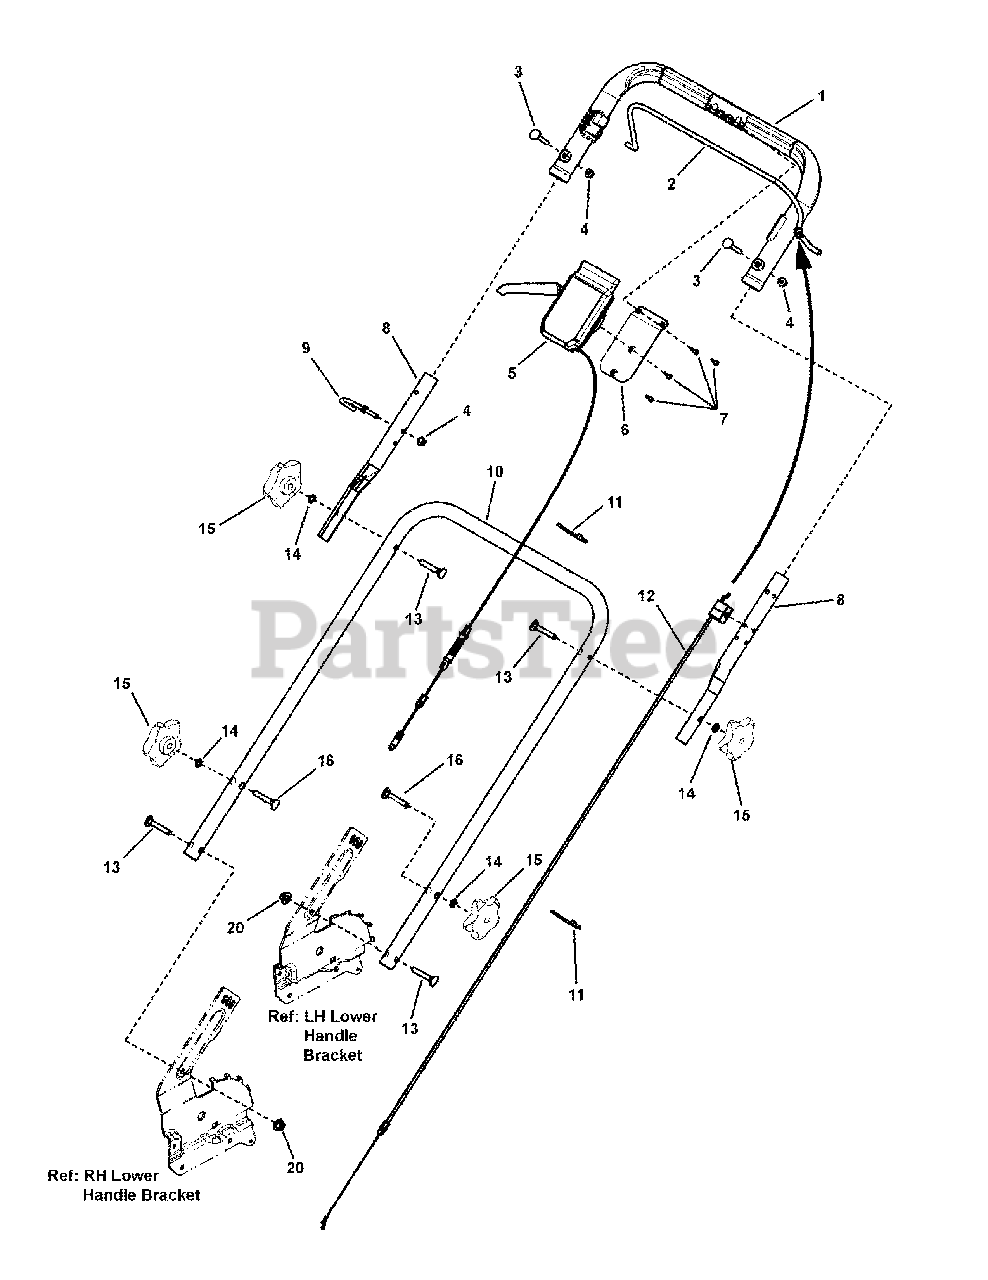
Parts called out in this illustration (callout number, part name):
1	UPPER HANDLE, Plastic, WBM
2	BAIL, Plastic Handle, WBM
3	BOLT, 1/4-20 x 1-3/4" Round Head Square Neck, GR 2, YZ
4	NUT, 1/4-20, Hex Flange (Nyloc) YZ
5	ASSEMBLY, Control Head, 22" WBM, VS, Hi-Wheel
6	PLATE, Control Panel, Plastic Handle
7	SCREW, Pan Head Cross Recess, Self-Tap
8	HANDLE, Connecting, 21"/22" WBM
9	ROPE GUIDE
10	HANDLE, Lower, 22" WBM, Hi-Wheel
11	WIRE TIE, 11 Inch Standard Black Nylon
12	CABLE, Bail, 22" WBM
13	BOLT, 5/16-18 x 2" Curved Head Square Neck, GR 2
14	WASHER, 5/16" Internal Tooth Lock
15	KNOB, 5-Prong, 5/16-18
16	CARRIAGE BOLT, 5/16-18 x 1-3/4, G5
20	NUT, 5/16-18 Large Flange Center Lock
